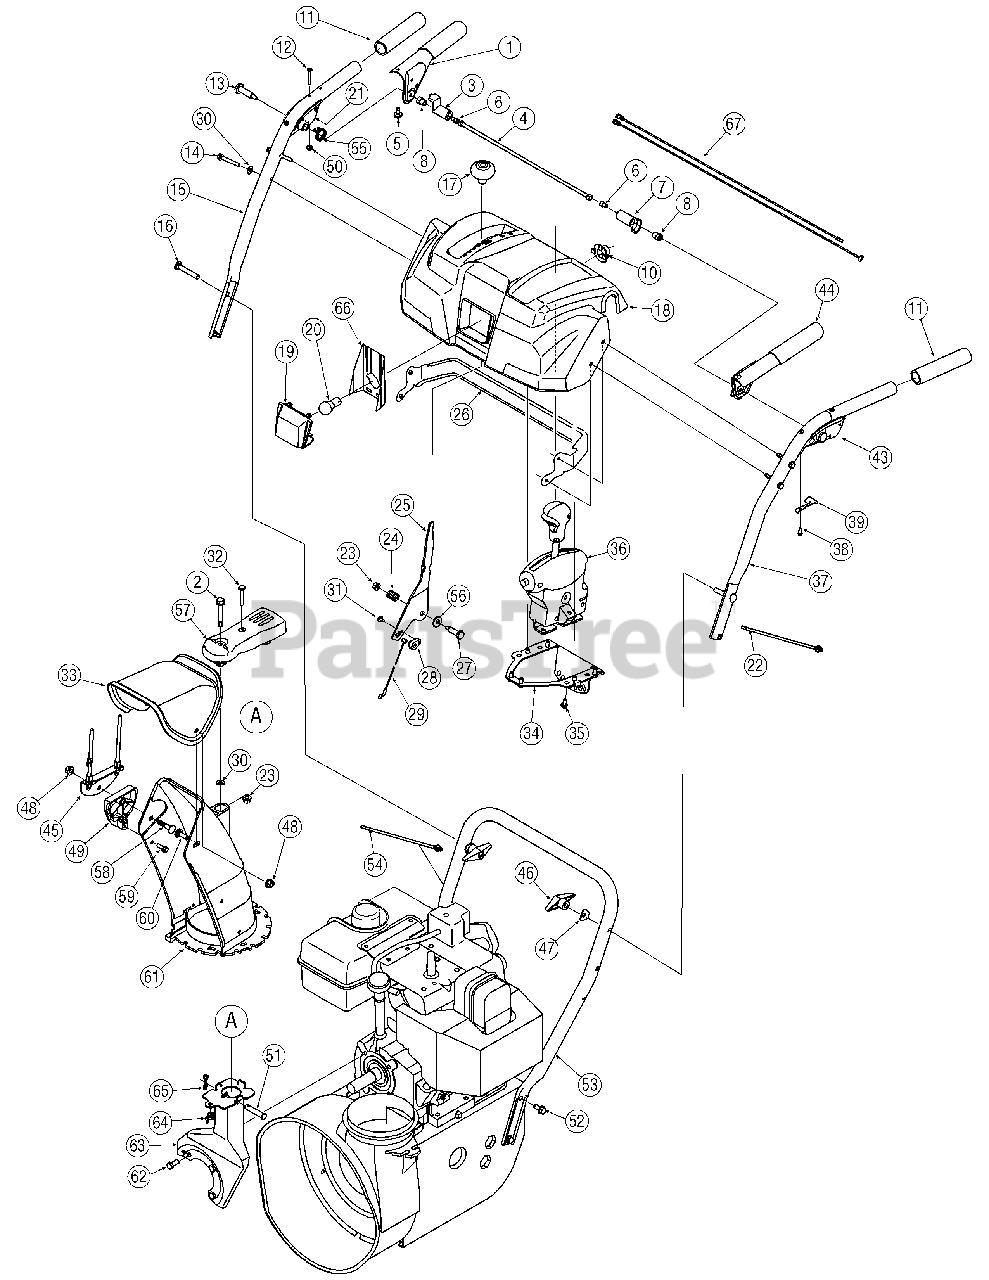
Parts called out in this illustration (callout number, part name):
1	Handle Engagement Assembly RH
2	Flange Shoulder Screw
3	Lock Plate
4	Pivot Rod
5	Rubber Bumper
6	Screw, 1/4-20 x.375
7	Clutch Lock Cam
8	Shoulder Nut, 1/4-20
10	Light Socket
11	Handle Grip
12	Screw, #10-24 x 0.375
13	Shoulder Screw, 1/4-20 x 1.345
14	Screw, 1/4-20 x 1.750
16	Carriage Screw, 5/16-18 x 2.25
17	Shift Knob
18	Handle Panel (P/Q-Style)
20	Lamp
21	Handle Clutch Lock - RH
22	Cable Tie
23	Flange Lock Nut, 1/4-20
24	Compression Spring
28	Cable Barrel Holder
29	Speed Selector Cable
30	Flat Washer, .25 x .630 x.0515
31	Screw, #10-16 x .500
32	Hex Screw, 1/4-20 x 1.50
33	Upper Chute
35	Hi-Lo Screw, 1/4-15 x 0.5
36	Chute Control Ass’y (Inc. Ref #57)
38	Screw, #8-16 x 0.50
39	Clutch Lock Spring
40	Steering Control
43	Handle Clutch Lock - LH
44	Handle Engagement Assembly LH
46	Handle Knob Assembly
47	Saddle Washer
48	Flange Lock Nut, 5/16-18
49	Chute Tilt Cable Guide
50	Hex Lock Nut, #10-24
52	AB Screw, 5/16-18 x 0.75
54	Cable Tie
55	Torsion Spring
56	Flat Washer
57	Joystick Pulley Cover
58	Carriage Bolt, 5/16-18 x 1.50
59	Hi-Lo Screw, 1/4-15 x .75
60	Carriage Bolt, 5/16-18 x 1.0
61	Lower Chute
62	Hex Screw, 5/16-24 x .750
65	Bow Tie Cotter Pin
66	Label, Lens Reflector
67	Wire Harness, Lamp
